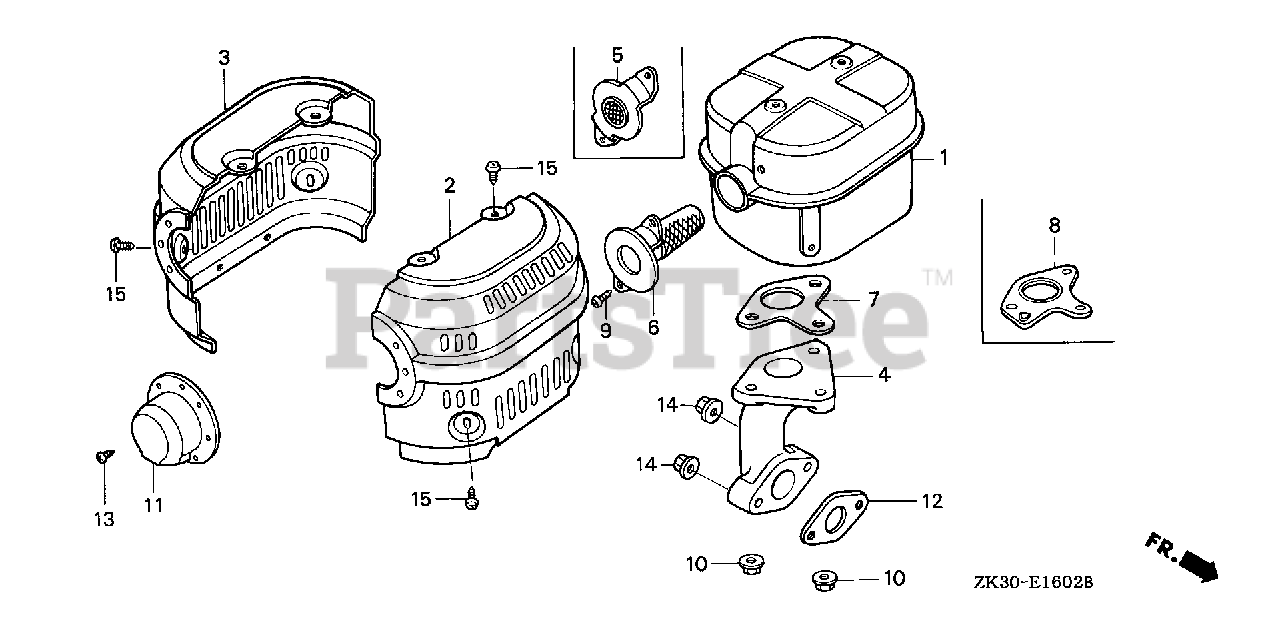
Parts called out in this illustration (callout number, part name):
2	PROTECTOR, R. MUFFLER (ALUMINIZED)
3	PROTECTOR, L. MUFFLER (ALUMINIZED)
5	FLANGE, BAFFLE
7	GASKET, MUFFLER (NIPPON LEAKLESS)
9	SCREW, TAPPING (5X8)
10	NUT, FLANGE (8MM)
12	GASKET, EX. PIPE
15	SCREW, TAPPING (5X8)
